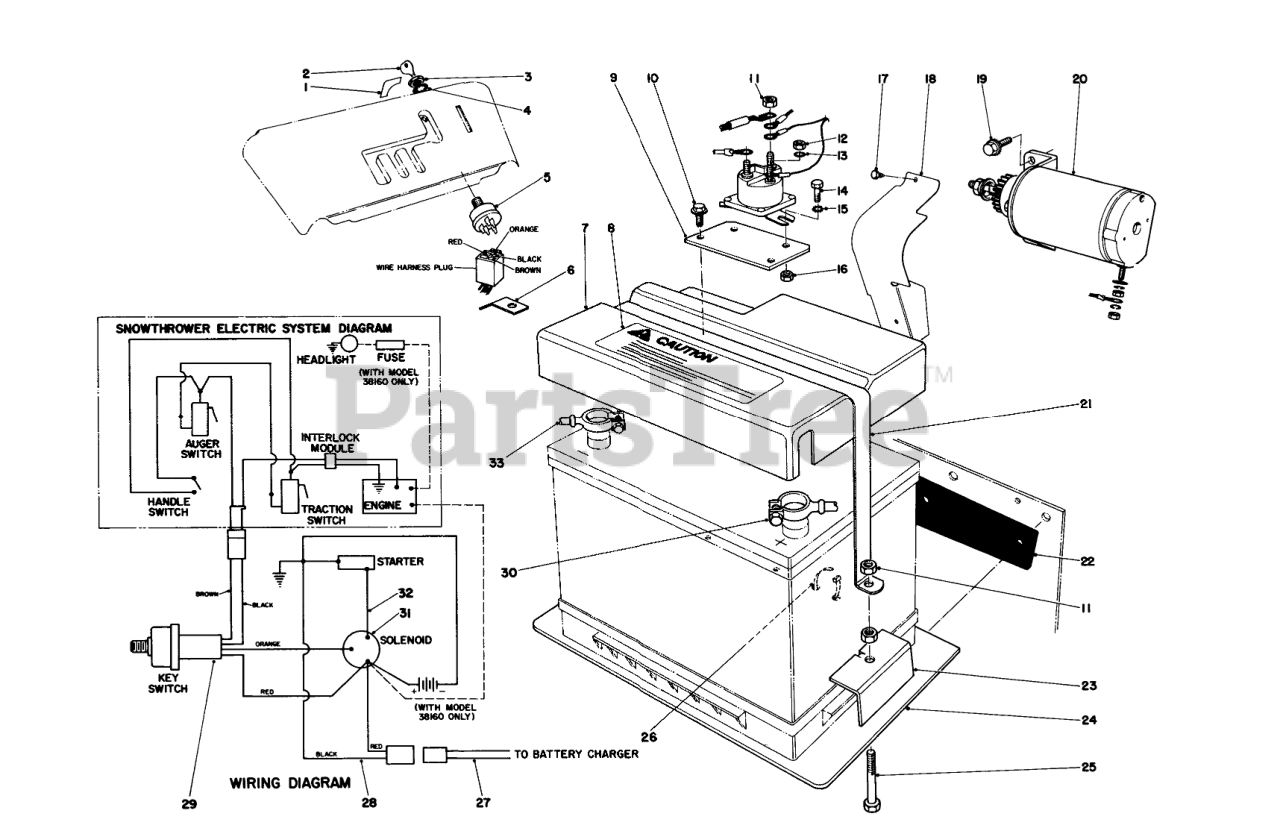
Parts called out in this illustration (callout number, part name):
1	Decal Switch
2	Key
3	NUT-HH
4	WASHER-TOOTH, INTERNAL
5	Starter Switch (Incl.Ref. #3 & 4)
6	Bracken Wire Clamp
7	Battery Cover(Incl.Ref. #8)
8	Decal-Caution
9	Bracket Solenoid
10	SCREW-HWH
11	NUT-HEX
12	NUT-HEX
13	WASHER-LOCK, INT
14	SCREW-HH
15	7 Lock washer
16	19 Nut
17	Hex Hd. Sems Screw
18	Pinion Shield
19	Screw-HH
20	Starter Motor & Pinion Assy.
21	Strap Battery
22	Batery Isolation Pad
23	BATTERY CLAMP
24	Battery Mounting Plate
25	SCREW-HH
26	TIE-CABLE
27	MALE WIRE ASM
28	FEMALE WIRE ASM
29	Wire Harness
30	BATT-SOLENOID CABLE
31	SOLENOID
32	STRT MTR-SOLNOID WIRE
33	BATT-GROUND CABLE
